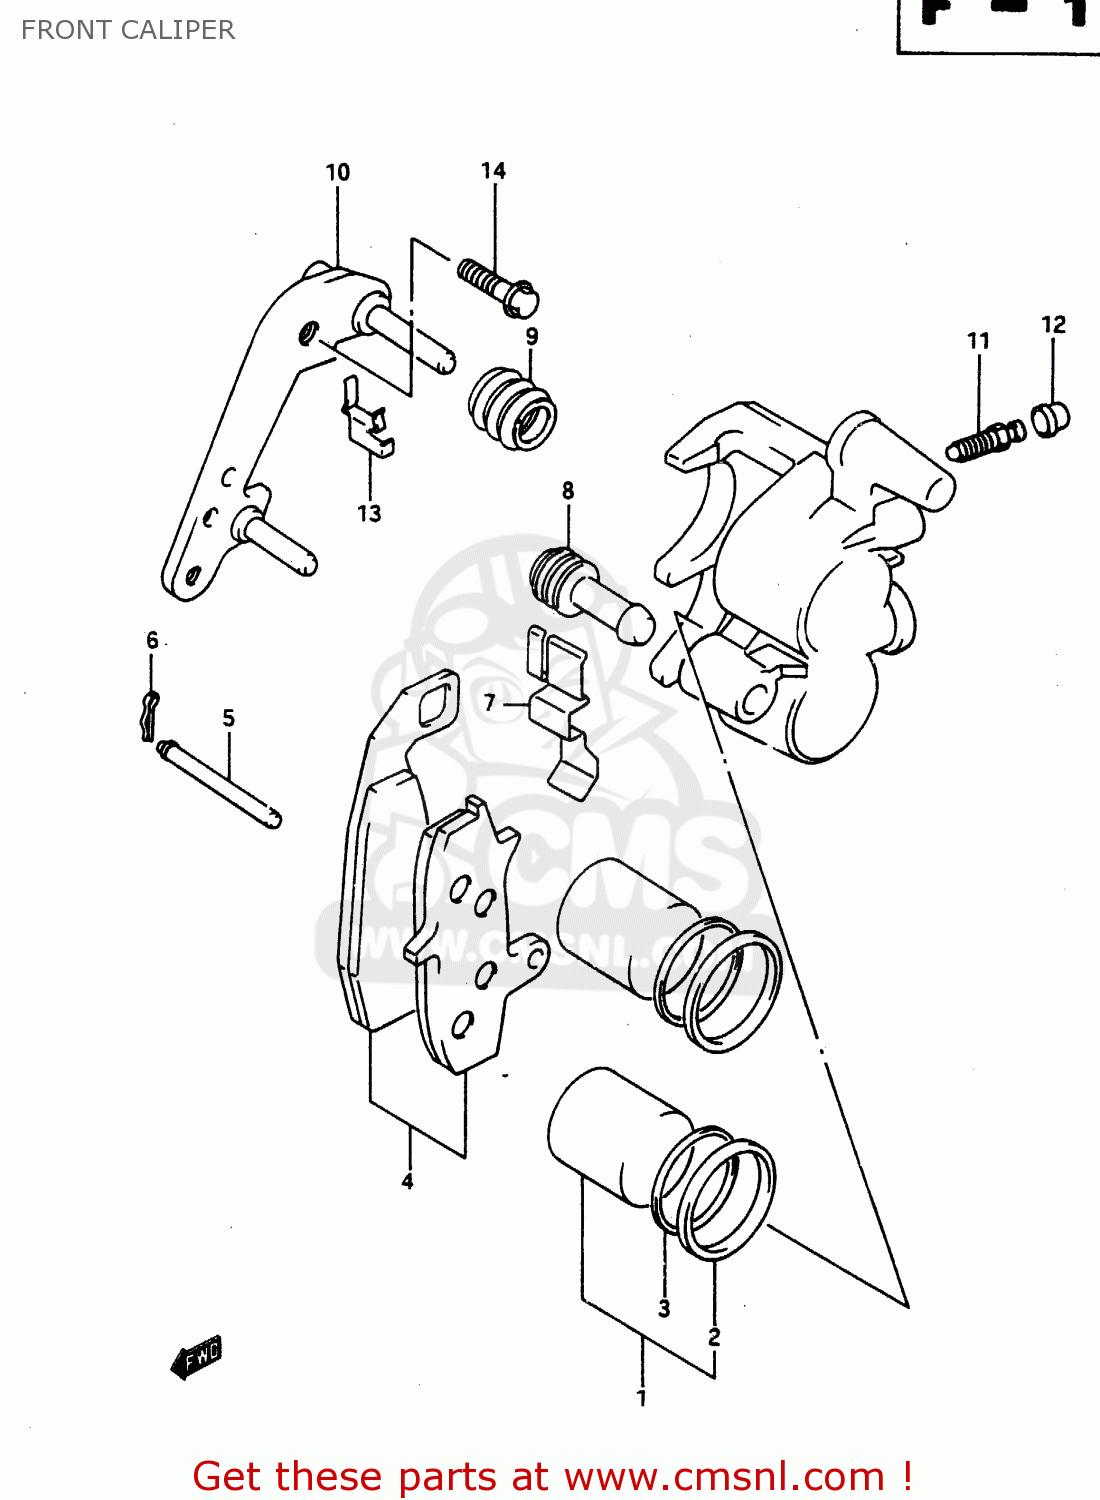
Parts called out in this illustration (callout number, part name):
1	PISTON SET
2	SEAL,PISTON
3	SEAL,WIPER
4	PAD SET (NAS)
5	PIN,PAD
6	CLIP,PAD PIN
7	SPRING,PAD
8	INSULATOR,AXLE
9	BOOT,AXLE
10	BRACKET
11	BLEEDER
12	CAP,BREATHER
13	GUIDE,PAD
14	BOLT
